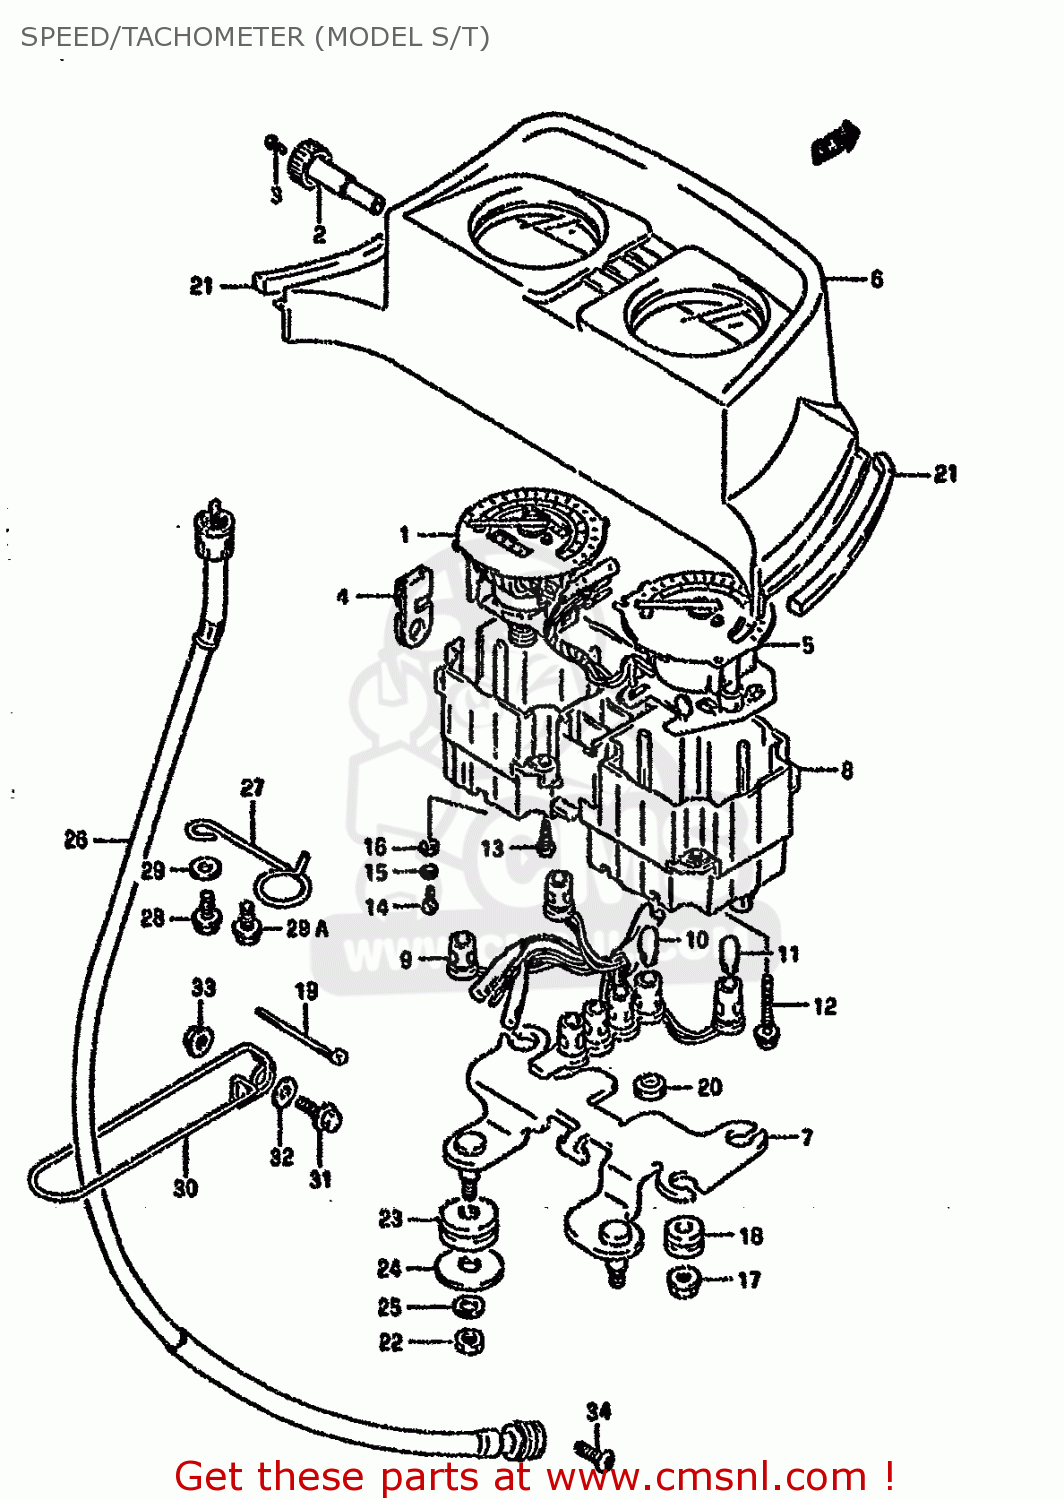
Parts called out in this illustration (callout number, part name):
1	SPEEDOMETER (KILO)
2	KNOB
3	SCREW,TRIP KNOB
4	CUSHION,METER
5	TACHOMETER
6	HOOD,METER
7	BRACKET
8	CASE,METER
9	SOCKET,METER
10	BULB(12V1.7W,WB372,T7)
11	BULB(12V3W,WB371,T7)
12	SCREW
13	SCREW
14	SCREW
15	WASHER,LOCK
16	WASHER
17	NUT
18	CUSHION,METER
19	CLAMP(L:97)
20	CAP
21	CUSHION,SPEEDOMETER
22	NUT 6MM
23	CUSHION
24	WASHER (6.5X24X1.6)
25	LOCK WASHER
26	CABLE ASSY,SPEEDOMETER
27	GUIDE,CABLE
28	BOLT
29	WASHER
29A	BOLT
30	GUIDE,METER CABLE
31	BOLT
32	WASHER(6.5X20X1.6)
33	NUT
34	SCREW
